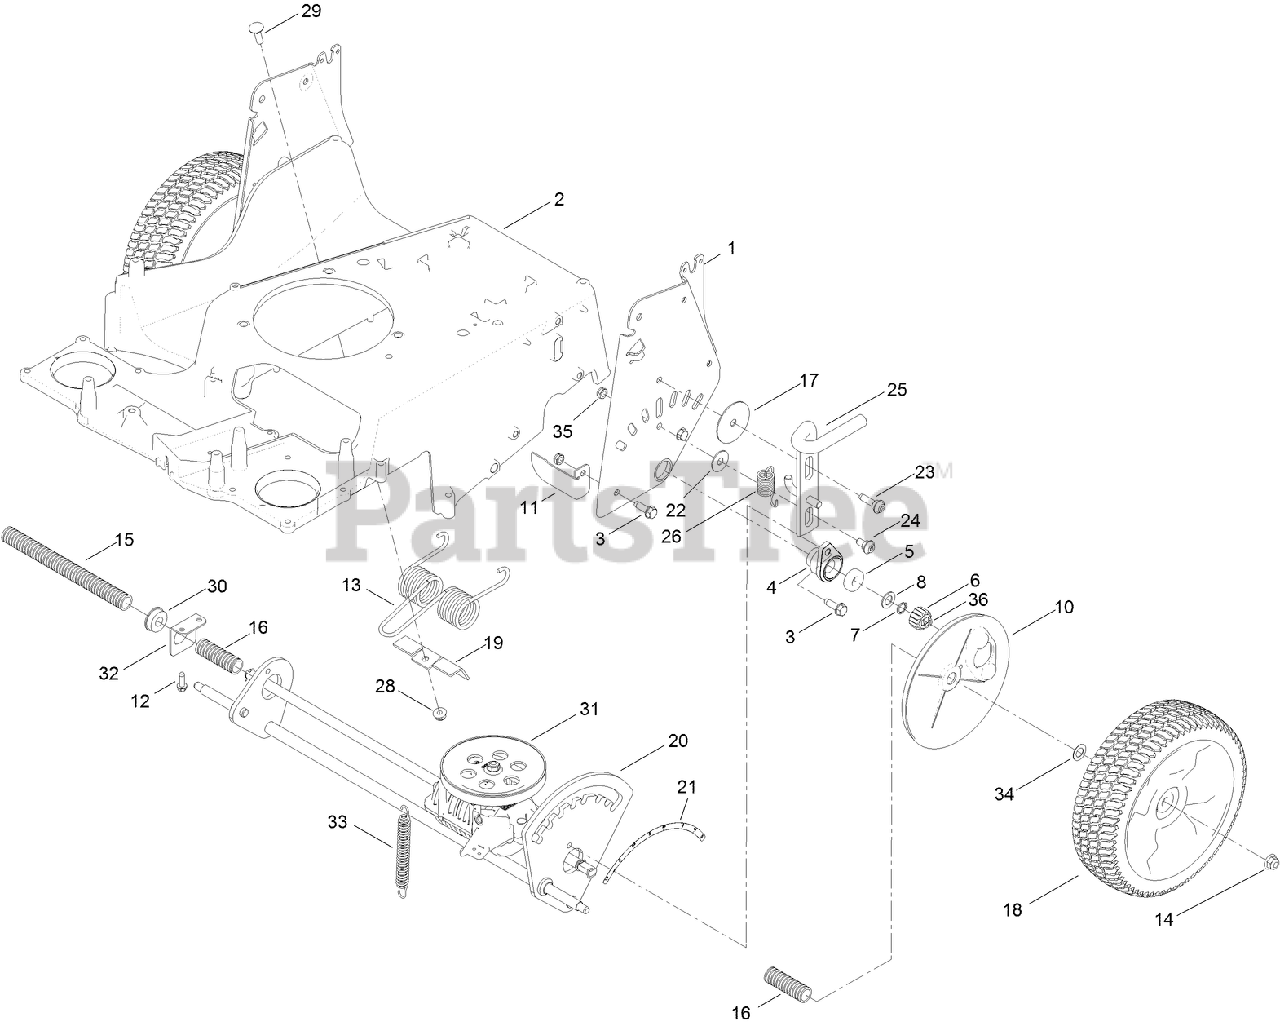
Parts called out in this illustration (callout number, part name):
1	LH HOC PLATE ASM
2	RH HOC PLATE ASM
3	SCREW-HWHTF
4	RETAINER-BEARING
5	BEARING-BALL
6	GEAR-PINION, 15T
7	RING-RETAINING
8	WASHER-THRUST
10	COVER-GEAR
11	BRACKET-STOP
12	SCREW-HWHTF
13	SPRING-TORSION
14	NUT-HF, NI
15	CONDUIT-CONVOLUTED
16	CONDUIT-CONVOLUTED
17	WASHER-PLAIN
18	10 INCH REAR WHEEL ASM
19	BRACKET
20	AXLE-REAR
21	DECAL-HOC, REAR
22	WASHER
23	SCREW-SHOULDER, BHTF
24	BOLT-SHOULDER
25	LOCK-HEIGHT, ADJUST
26	SPRING-EXTENSION
28	NUT-HF, NI
29	BOLT-CARR
30	BEARING-BALL
31	TRANSMISSION KIT
32	MOUNT-BEARING
33	SPRING-EXTENSION
34	WASHER-PLAIN
35	NUT-LOCK, NI
36	PIN-SNAP
